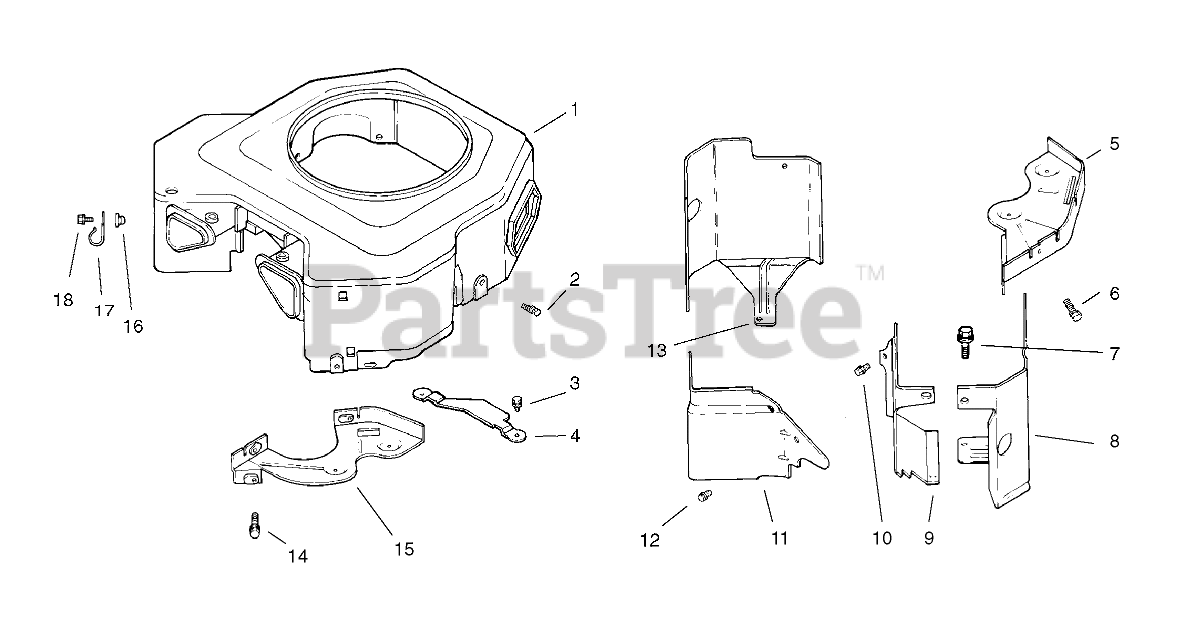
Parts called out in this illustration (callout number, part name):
1	Blower Housing ASM
2	Screw
3	Screw
4	Guard-Flywheel
5	Plate-Backing #2 Side
6	Screw
7	Screw
8	Baffle-Cylinder, #2
9	Baffle-Valley #1 Side
10	Screw
11	Baffle-Valley #2 Side
12	Screw
13	Baffle-Cyl. #1 Side
14	Screw
15	Plate-Backing #1
16	Nut
17	Clamp
18	Screw
